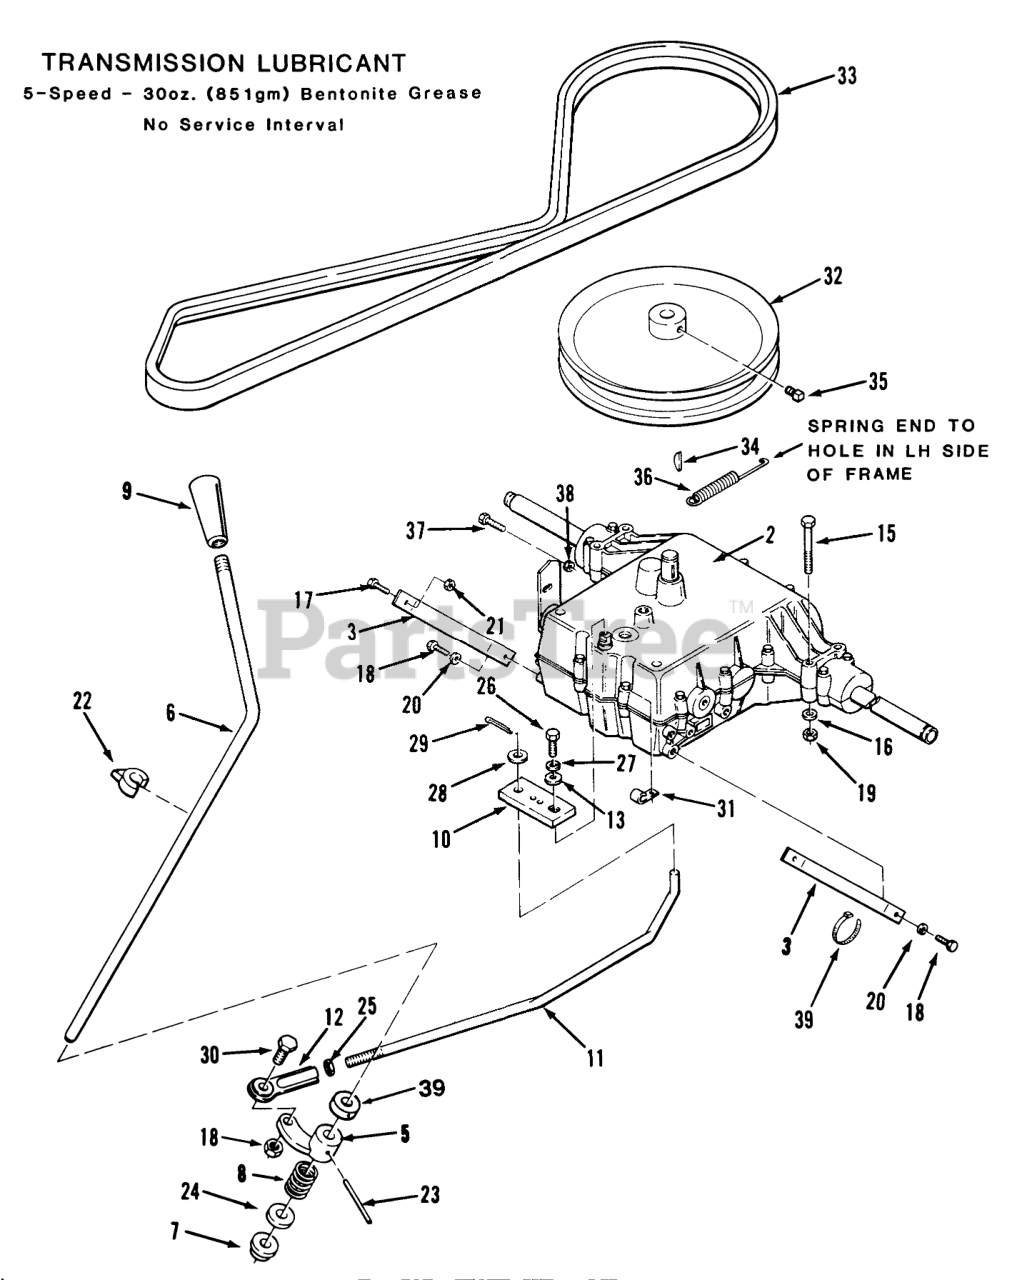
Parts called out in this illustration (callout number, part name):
2	ASS'Y TRANSAXLE 5-SP
3	TORQUE-STRAP R
5	ARM SHIFTER B
6	ROD-SHIFT LEVER
7	BUSHING-NYLINER
8	SPRING COMPRESSION
10	ARM-TRANSMISSION 5SP
11	ROD-LINKAGE
12	END-ROD
13	WASHER
15	SCREW-HH
16	WASHER-PLAIN
17	CARRIAGE BOLT -4
18	Screw
19	NUT-LOCK, NI
20	WASHER-LOCK
21	Nut
22	POINTER
23	SPIROL PIN 7/32X21/2
24	Washer
25	NUT-JAM
26	SCREW-HH
27	WASHER-LOCK
28	WASHER 5/16 SAE
29	PIN-COTTER
30	SCREW-HH
31	J-CLIP
32	PULLEY-TRANS
33	BELT-V
34	KEY-HI-PRO
35	SCREW-SQH
36	SPRING-EXTENSION
37	SCREW-HH
38	Nut
39	PLASTIC TIE
40	COLLAR
